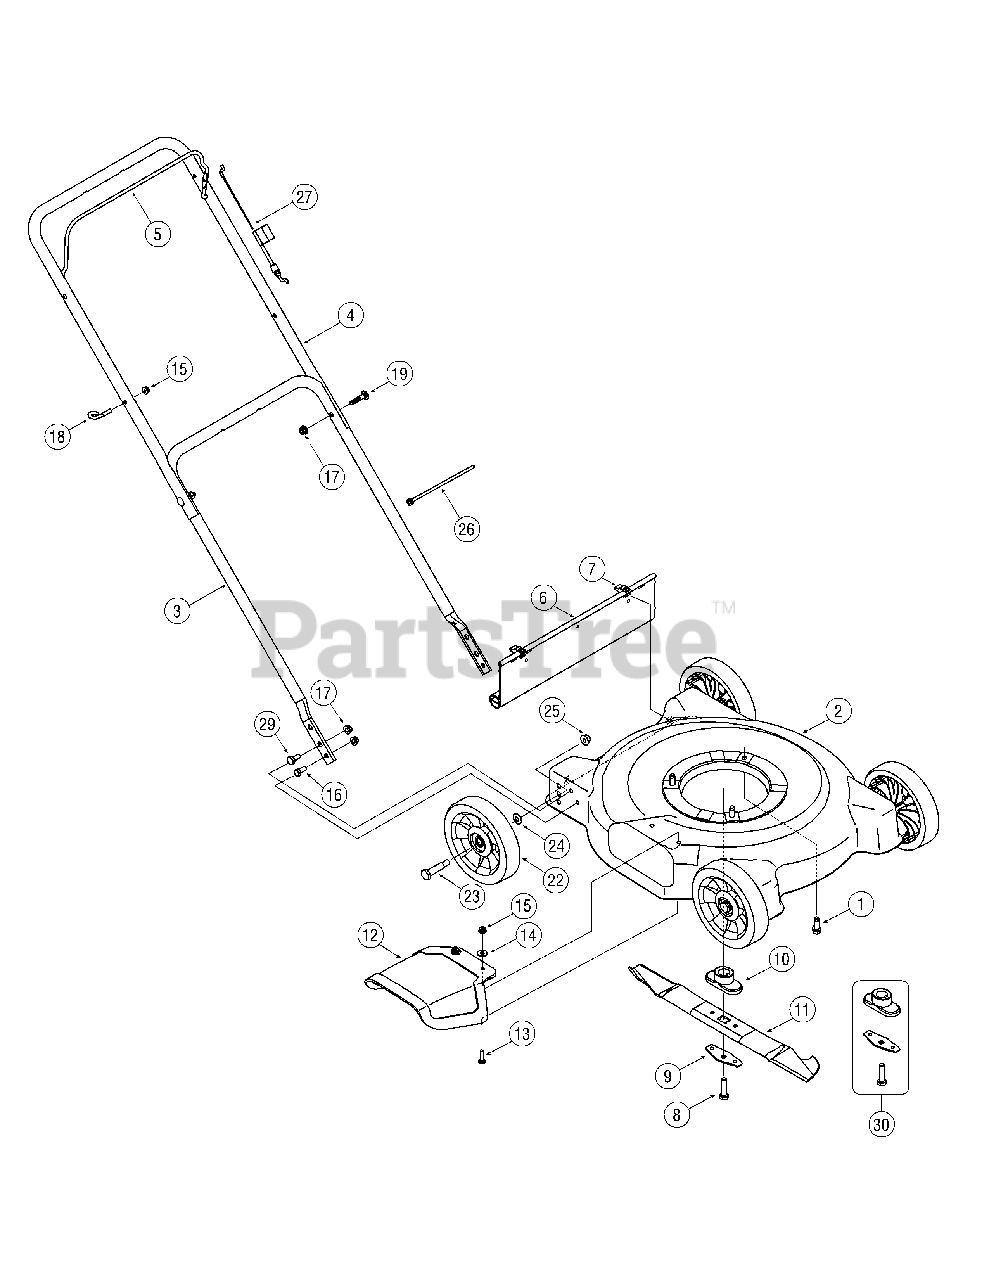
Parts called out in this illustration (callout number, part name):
1	Hex Wash HD Tap Scr 3/8-16 x .88
2	20" Deck w/sprig logo
4	Upper Handle
5	Blade Control Handle
6	Rear Flap
7	Hinge Clip
8	Hex Bolt 3/8-24 x 1.5" Lg. (Gr 8)
9	Blade Bell Support
10	Blade Adapter
11	Blade, Centre Star, 20"
12	Fixed Side Chute
13	Carriage Bolt 1/4-20 x 1.00" Lg.
14	Flat Washer .28 ID x .74 OD x .063
15	Flanged Lock Nut 1/4-20 Gr. F Ny lon
16	Hex Bolt 5/16-18 x .75" Lg. Gr. 5
17	Flanged Lock Nut 5/16-18 Gr. F Ny lon
18	Rope Guide Bolt
19	Carriage Bolt 5/16-18 x 1.50 Gr. 2
22	Wheel Ass’y 7" Star Diamond Grey
23	Shoulder Screw .498" DIA. x 1.64
24	Cupped Washer .375 ID x .870 OD x .063
25	Flanged Lock Nut 3/8-16 Gr. F Nylon
26	Cable Tie
27	Control Cable 48.25" Lg. (Tec)
29	Shoulder Screw, 3/8-16 x .428
30	Blade Adapter Kit
